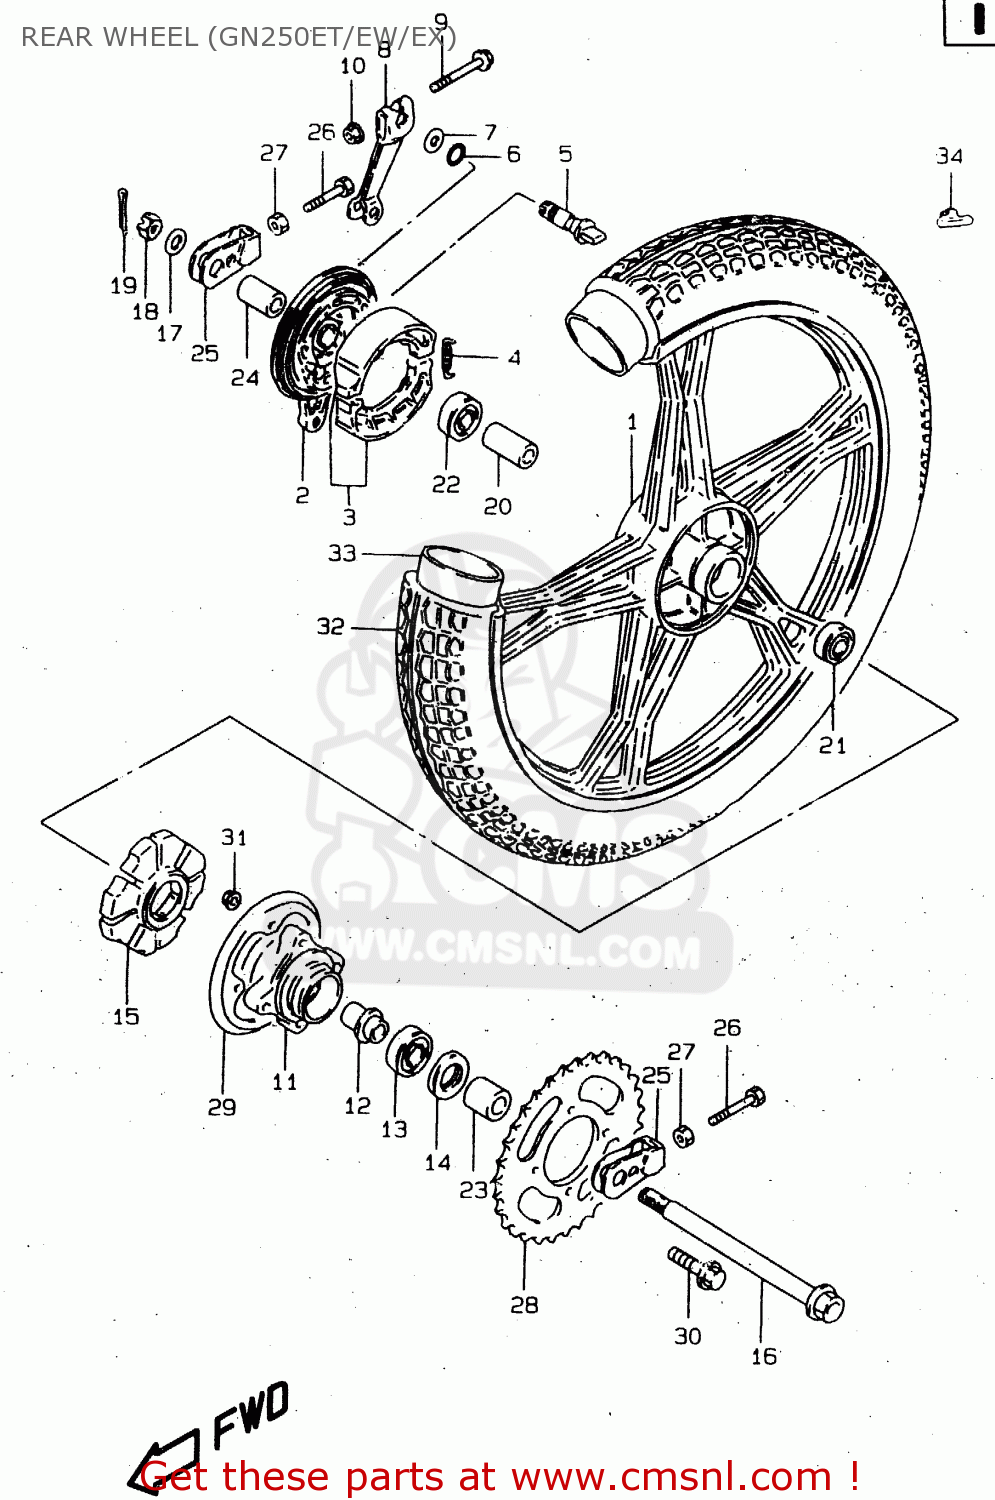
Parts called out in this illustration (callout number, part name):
1	WHEEL,RR(2.15X10)
2	PANEL,RR BRAKE ANCHOR
3	SHOE SET,BRAKE (NAS)
4	SPRING(L:34)
5	CAM,BRAKE
6	O RING(D:2.5,ID:13.8)
7	WASHER(14.5X22X1.6)
8	LEVER,RR BRAKE CAM
9	BOLT
10	NUT
11	DRUM,RR SPROCKET MOUNTING
12	RETAINER,RR SPROCKET DRUM
13	BEARING(20X47X14)
14	SEAL,OIL(28X47X7)
15	ABSORBER,RR HUB SHOCK
16	AXLE,REAR
17	WASHER
18	NUT
19	COTTER PIN
20	SPACER(15.3X21.7X63)
21	BEARING
22	BEARING
23	SPACER(15X28X24.8)
24	SPACER(15X22X46.8)
25	ADJUSTER,CHAIN
26	BOLT(8X50)
27	NUT
28	SPROCKET,RR(NT:41-520)
29	GUIDE,RR SPROCKET CHAIN
30	BOLT(10X40)
31	NUT
32	TIRE
33	TUBE ASSY,WHEEL,INNER 4.60-16
34	BALANCER,WHEEL (10G)
